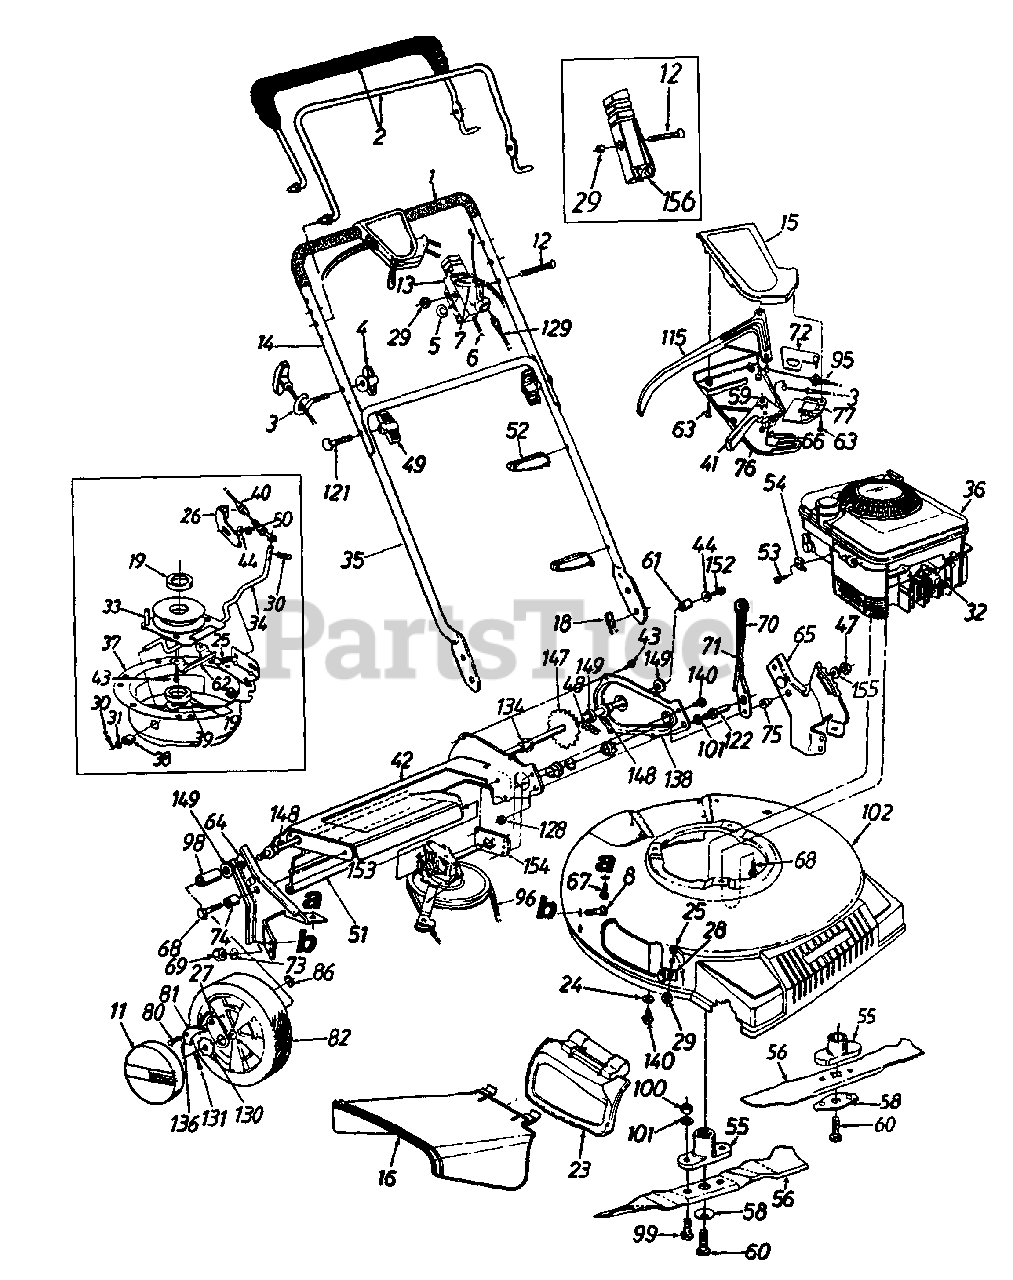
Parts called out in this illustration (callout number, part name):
1	Grip
3	Rope Guide
4	Handle Knob 1/4-20 Thd.
5	Curved Spring Wash. .66" I.D.
6	Throttle Wire - 55" Lg.
7	Throttle Lever
8	Carriage Bolt 5/16-18 x .62" Lg.
11	Hub Cap
12	Oval C-Sunk Mach. Scr.
13	Throttle Body
15	Upper Control Housing
16	Side Chute Deflector
18	Internal Cotter Pin 5/16" Dia.
19	Spacer .88" l.O.
23	Mulch Plug Ass'y.
24	Bell-Wash..265" I.D. x .75" O.D.
25	Carriage Bolt 1/4-20 x .5" Lg.
30	Cotter Pin 3/32" Dia. x .75"
31	Fl-Wash..328" I.D. x .68"
32	Spark Plug Insulator
33	Pulley Ass'y.
34	Shift Rod
36	Engine
39	Wave Washer .88" I.D.
40	6 Spd. Cable
41	6 Spd. Shift Lever
44	Bell-Wash. 1/4" I.D.
47	Hex Patch L-Nut 3/8-24 Thd.
48	#48 Chain .500" Pitch x 38 Links
49	Hand Knob
50	Hex L-Nut 1/4-20 Thd.
51	Rear Flap 4.8" x 17.5" Lg.
52	Cable Tie
53	Hex Wash. Hd. Scr. #10-32 x .62" Lg.
54	Casing Clamp
55	Blade Adapter
56	21" Mulching Blade
58	Bell-Wash..39" I.D x 1.14" O.D.
59	Gear Insert
60	Hex Bolt 3/8-24 x 2.5" Lg. (Gr. 8)
61	Spacer .513" I D.
67	Hex B-Tap Scr. 5/16-18
68	Hex TT-Tap Scr 3/8-16
69	Hex Nut 5/16-18 Thd.
71	Height Adj. Lever
72	6 Spd. Rack Cable Brkt.
73	Bell-Wash. 5/16" I.D.
74	Spacer .383" I. D
75	Shld. Spacer .5" Dia.
76	Lower Control Housing
77	Cable Mounting Cap
80	Shld. Scr..342" Dia. x .268
81	Pawl - R.H.
82	Wheel Ass'y Comp. (Gray Rim)
86	Weld Top L-Nut 1/4-20 Thd.
95	S.P. Cable
96	"V"-Belt
98	Sleeve .526" I.D.
99	Hex Bolt 3/8-24 x 1.0" Lg.
100	Hex Nut 3/8-24 Thd.
101	L-Wash. 3/8" I.D.
121	Curved Hd. Bolt 5/16-18 x 2" Lg.
122	Shld. Pin 1.43" Lg.
128	Hex Jam Nut 3/8-24 Thd.
129	Control Cable - 39"
130	Ratchet Wheel 1.62" O.D.
131	Cotter Pin 1/8" Dia. x 1"
134	Hex Flange Bearing
136	Spring - Nylon
147	Rear Shaft Ass'y. 21.44" Lg.
148	Hex Flange Brg..506" I.D.
149	Fl-Wash..531" I.D. x .930"
152	Hex Bolt 1/4-20 x .62" Lg. (Gr. 5)
153	Transmission Comp.
155	Fl-Wash..385" I.D. x .87" O.D.
